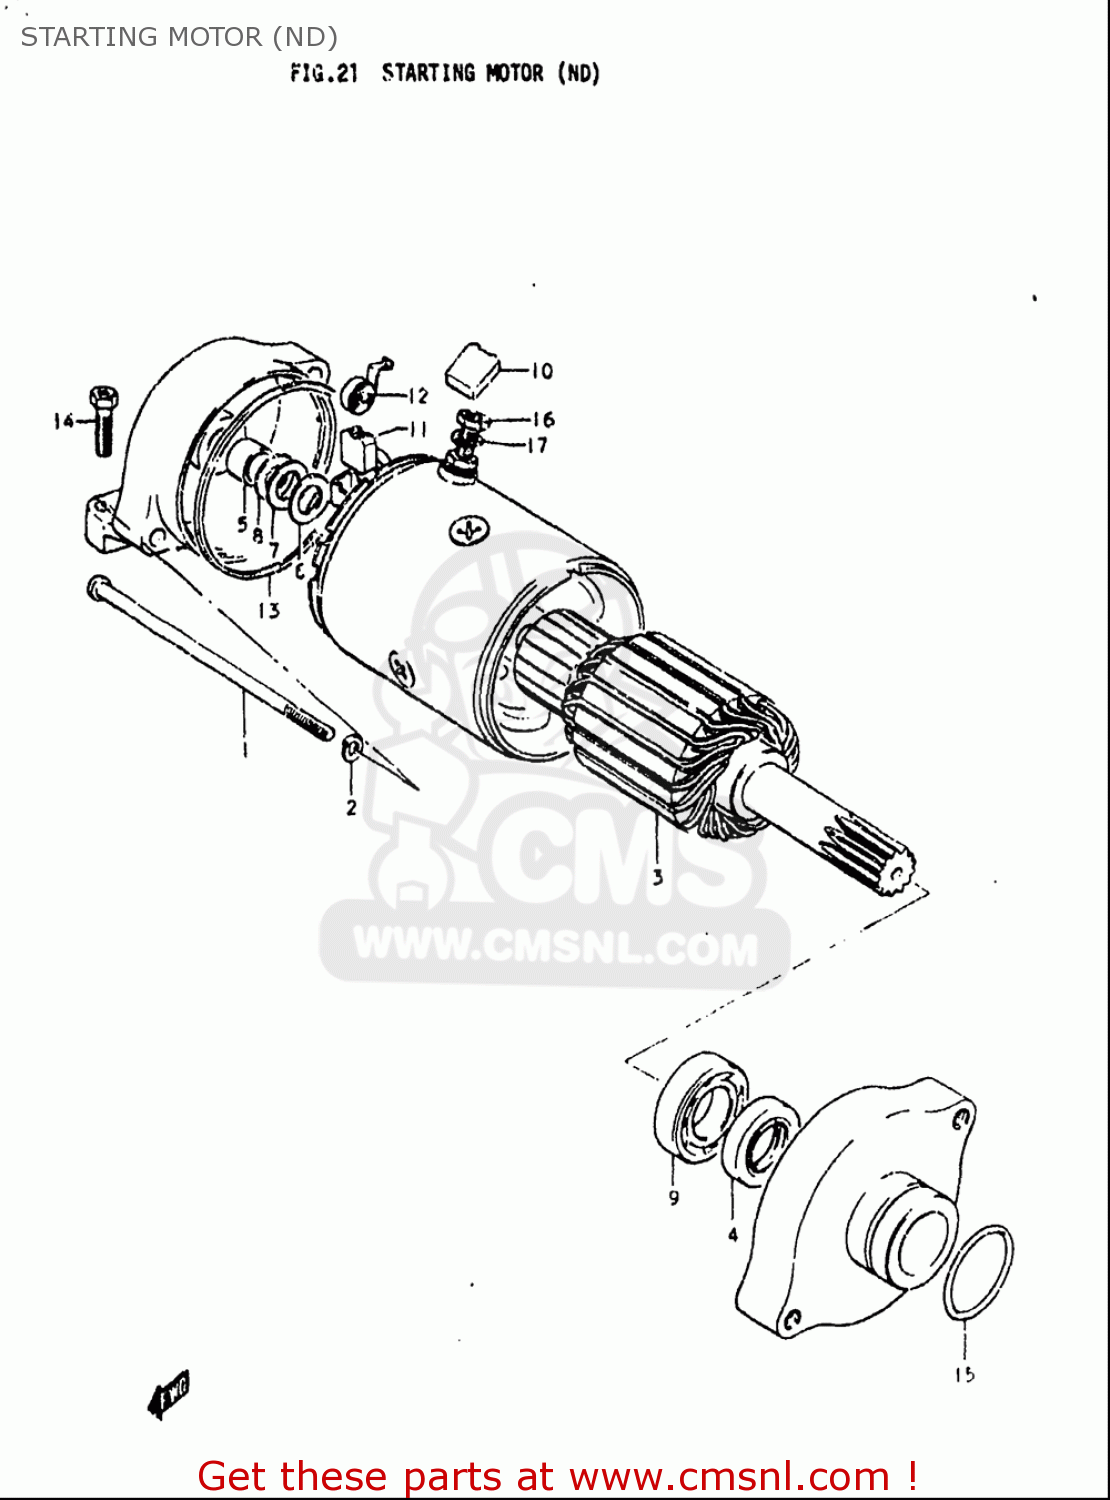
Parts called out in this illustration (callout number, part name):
2	WASHER,LOCK
4	SEAL,OIL
6	SHIM, (1)
7	SHIM, (2)
8	SHIM, (3)
9	BEARING
10	BRUSH(-)
12	SPRING
13	GASKET
14	SCREW (6X25)
15	O RING(D:2,ID:24.5)
16	NUT
17	WASHER,LOCK
